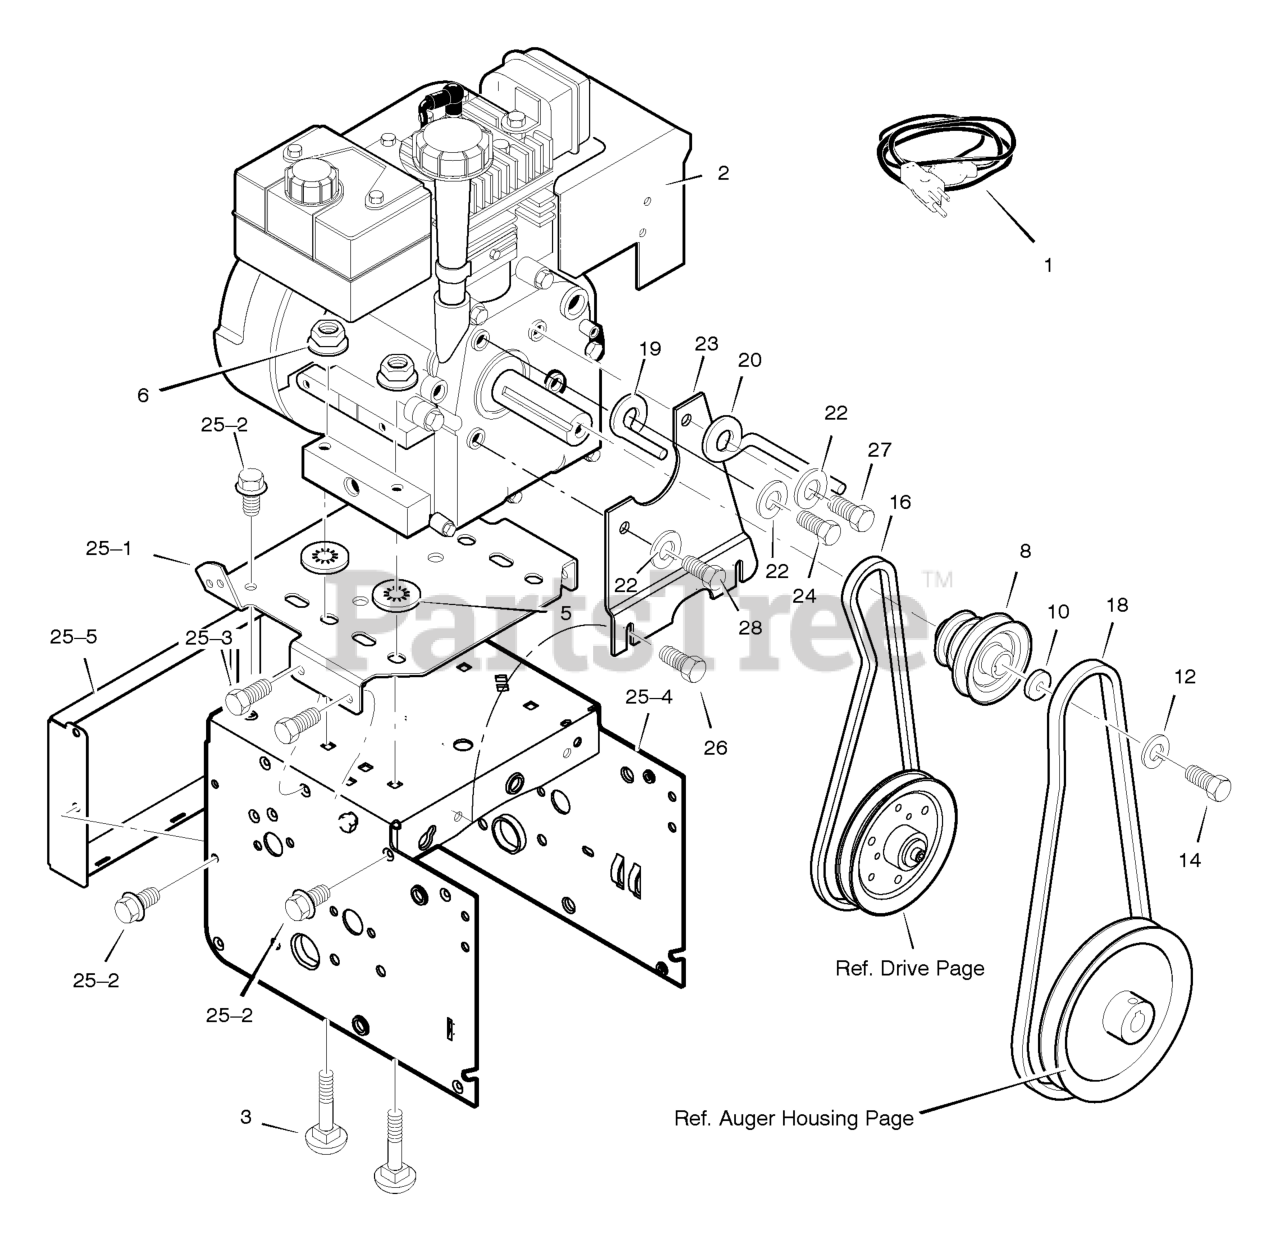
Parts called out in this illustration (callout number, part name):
1	CORD, Electric, 10FT. 110V
2	ENGINE
3	BOLT, CARRIAGE 5/16-18
5	RETAINER, PUSH
6	NUT, HEX 5/16-18
8	PULLEY, ENGINE
10	WASHER
12	WASHER
14	SCREW, 3/8-24 x 1.00
16	BELT, HYDRO DRIVE
18	BELT, AUGER V 4L
19	GUIDE, BELT
20	GUIDE, BELT
22	WASHER, .31X.58X.08
23	PLATE, VIBRATION
24	SCREW, 5/16-24 x 0.75
25	FRAME ASSEMBLY
25-1	PLATE, ENGINE MOUNT
25-2	SCREW, TAP 1/4-20 X .63
25-3	SCREW, TAP 5/16-18 X .50
25-4	FRAME, MOTOR BOX
25-5	PANEL, BACK - HYDRO
27	BOLT, HEX 5/16-24 X 1.00
28	BOLT, HEX 5/16-24 X 0.63
